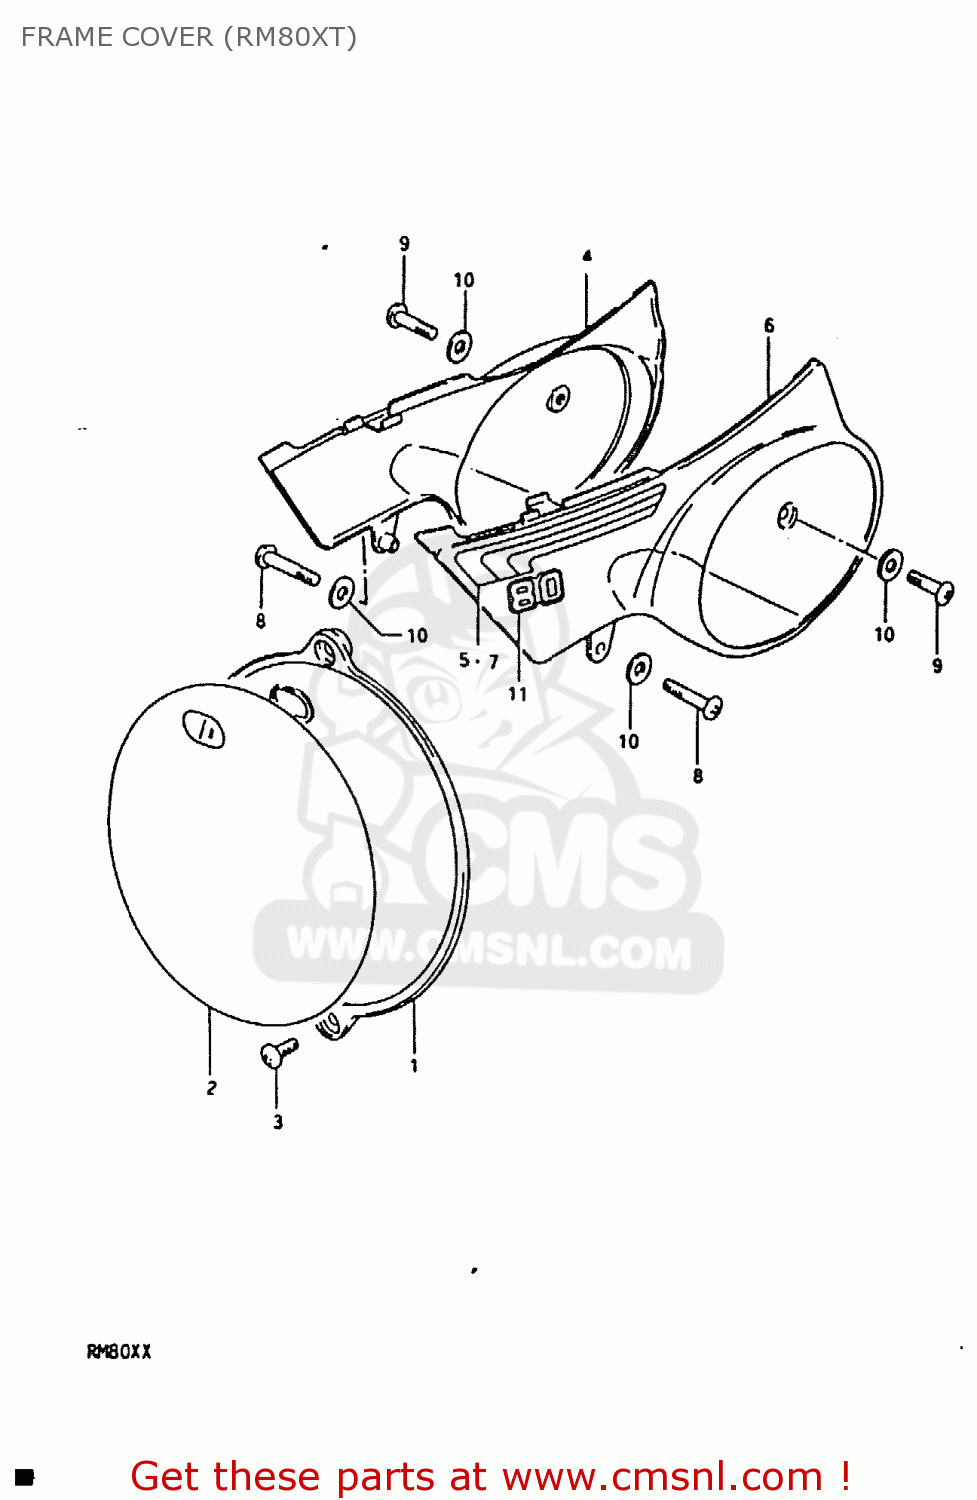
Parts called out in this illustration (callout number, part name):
1	PLATE,NUMBER,FRONT
2	EMBLEM,FRONT NUMBER PLATE
3	SCREW
4	COVER,FRAME,R(YELLOW)
5	TAPE,FRAME COVER,RIGHT STRIPE
6	COVER,FRAME,LEFT
7	TAPE,FRAME COVER
8	SCREW, NO. 1
9	SCREW
10	WASHER
11	EMBLEM
